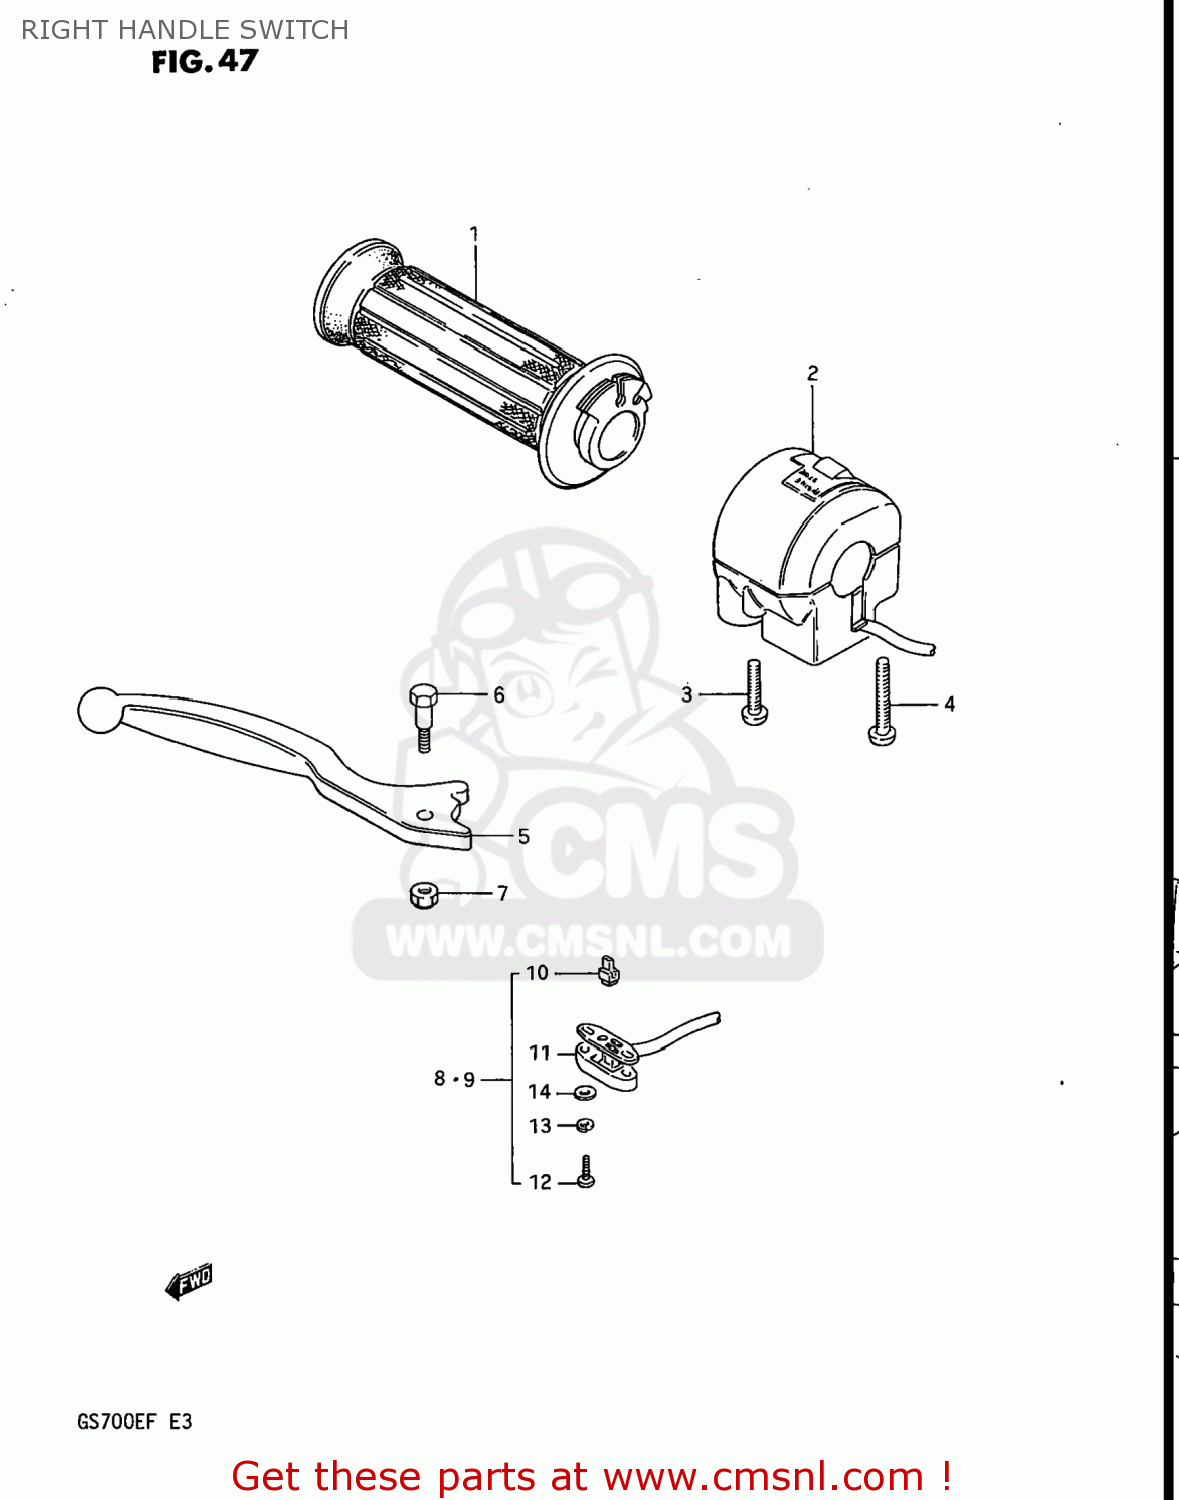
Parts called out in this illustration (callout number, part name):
1	GRIP,THROTTLE
2	SWITCH ASSEMBLY,HANDLE,RIGHT
3	SCREW
4	SCREW
5	LEVER,BRAKE
6	BOLT,LEVER PIVOT
7	NUT 6MM
8	SWITCH ASSY,STOP
9	SWITCH ASSEMBLY
10	CONTACT,SWITCH
11	COVER,FR BK TERMINAL BASE
12	SCREW
13	LOCK WASHER
14	WASHER
